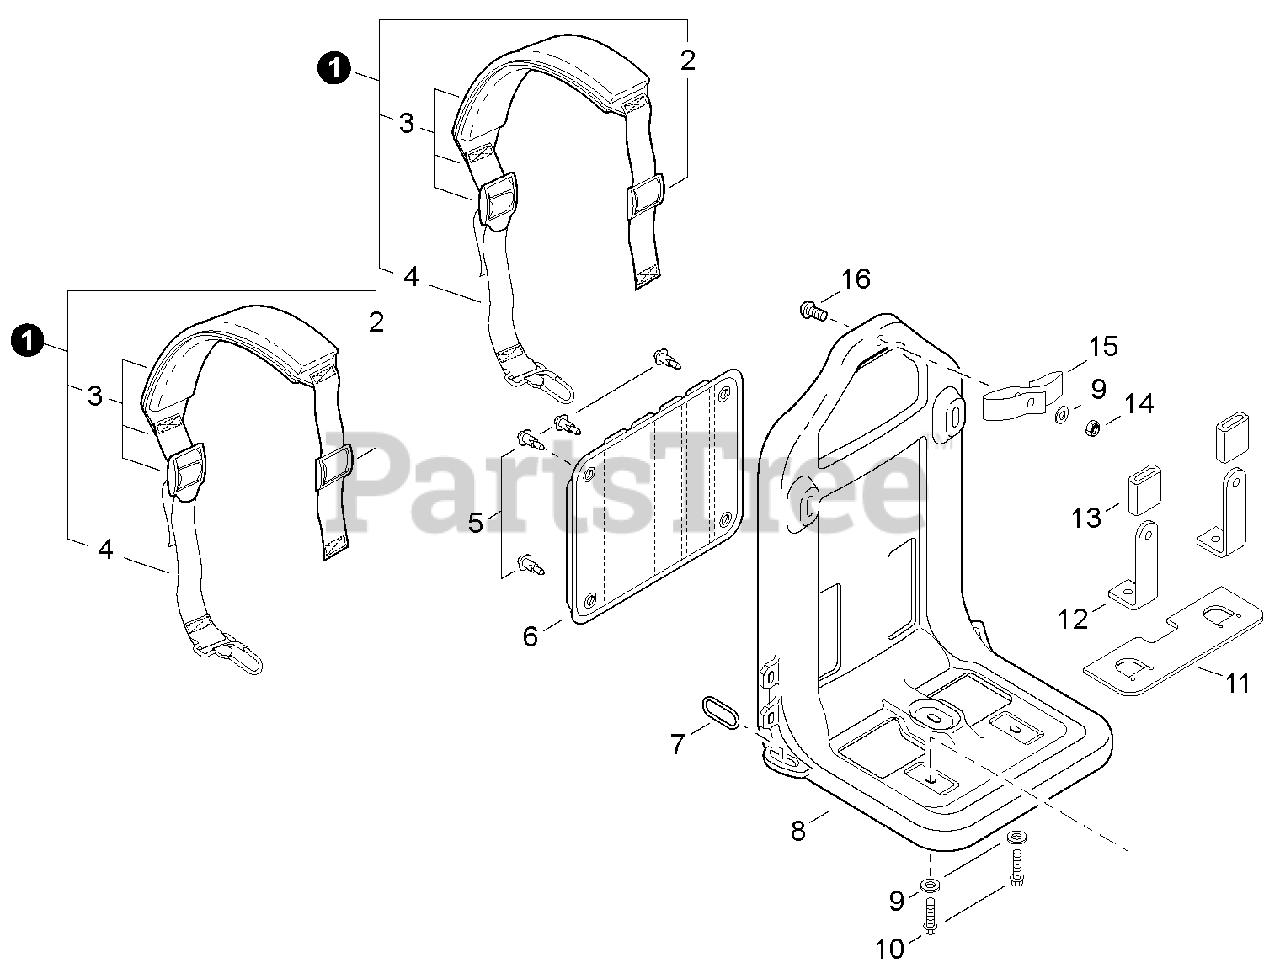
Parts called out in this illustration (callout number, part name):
1	STRAP KIT
2	BUCKLE
3	BACKPACK STRAP ASSY
4	STRAP
5	CLIP
6	CUSHION, BACKPACK
7	RING, HARNESS
8	FRAME, BACKPACK
9	COLLAR - 18
10	SCREW - 6X20
11	CUSHION
12	BRACKET
13	CUSHION
14	LOCKNUT - 6
15	HANGER
16	SCREW - 6X30
